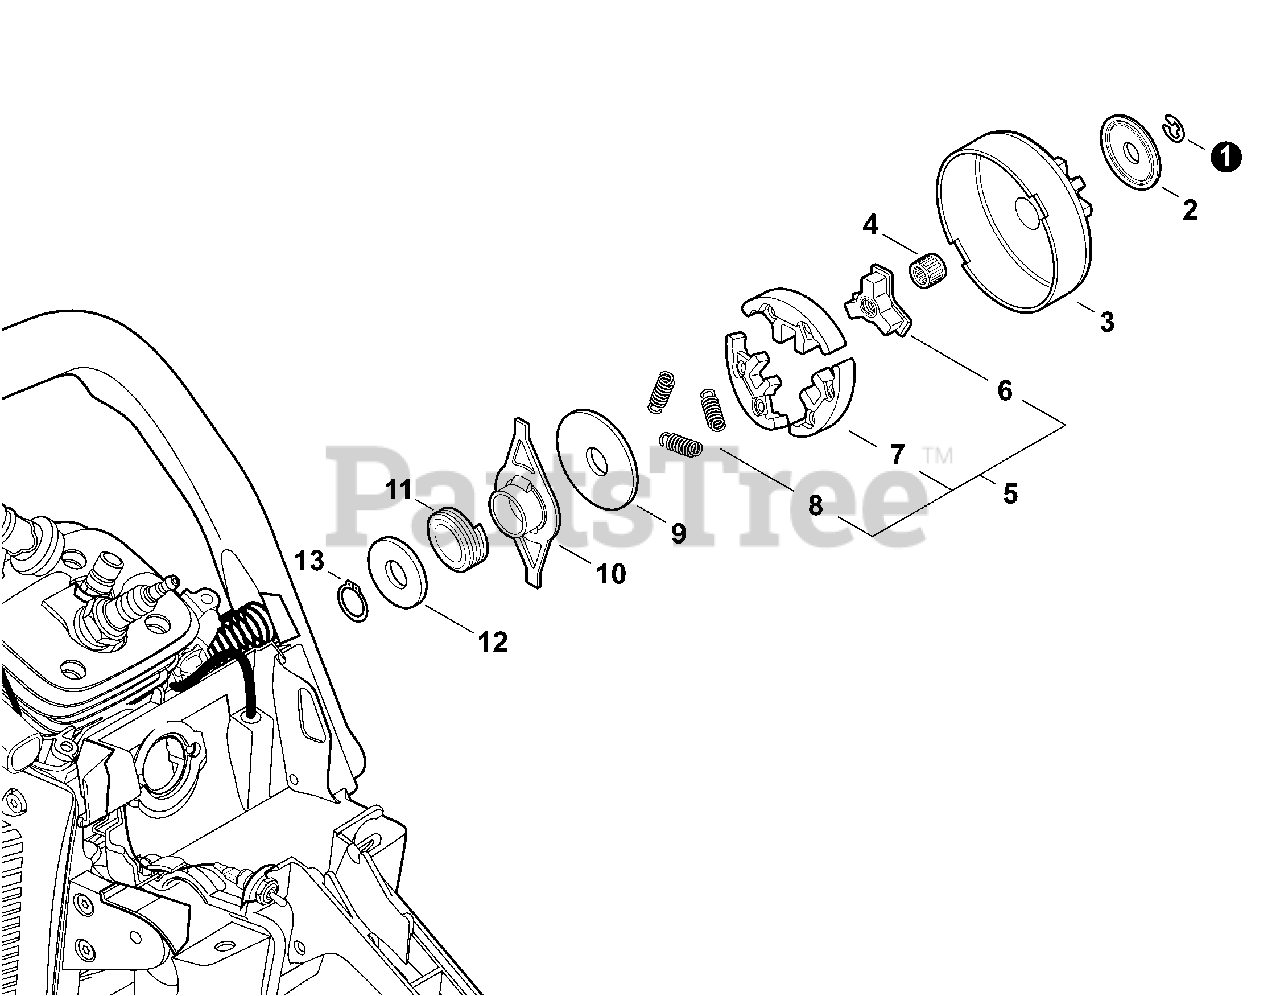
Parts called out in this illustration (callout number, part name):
1	E-RING Ø8.1
2	WASHER 10
3	DRUM, CLUTCH
4	BEARING, NEEDLE 10
5	CLUTCH ASSY
6	HUB, CLUTCH
7	SHOE SET, CLUTCH (3PCS)
8	SPRING, TENSION
9	PLATE, CLUTCH
10	COLLAR 15×19×73
11	GEAR, WORM
12	WASHER 15.5×22.5×0.5
13	RING, RETAINING 15
